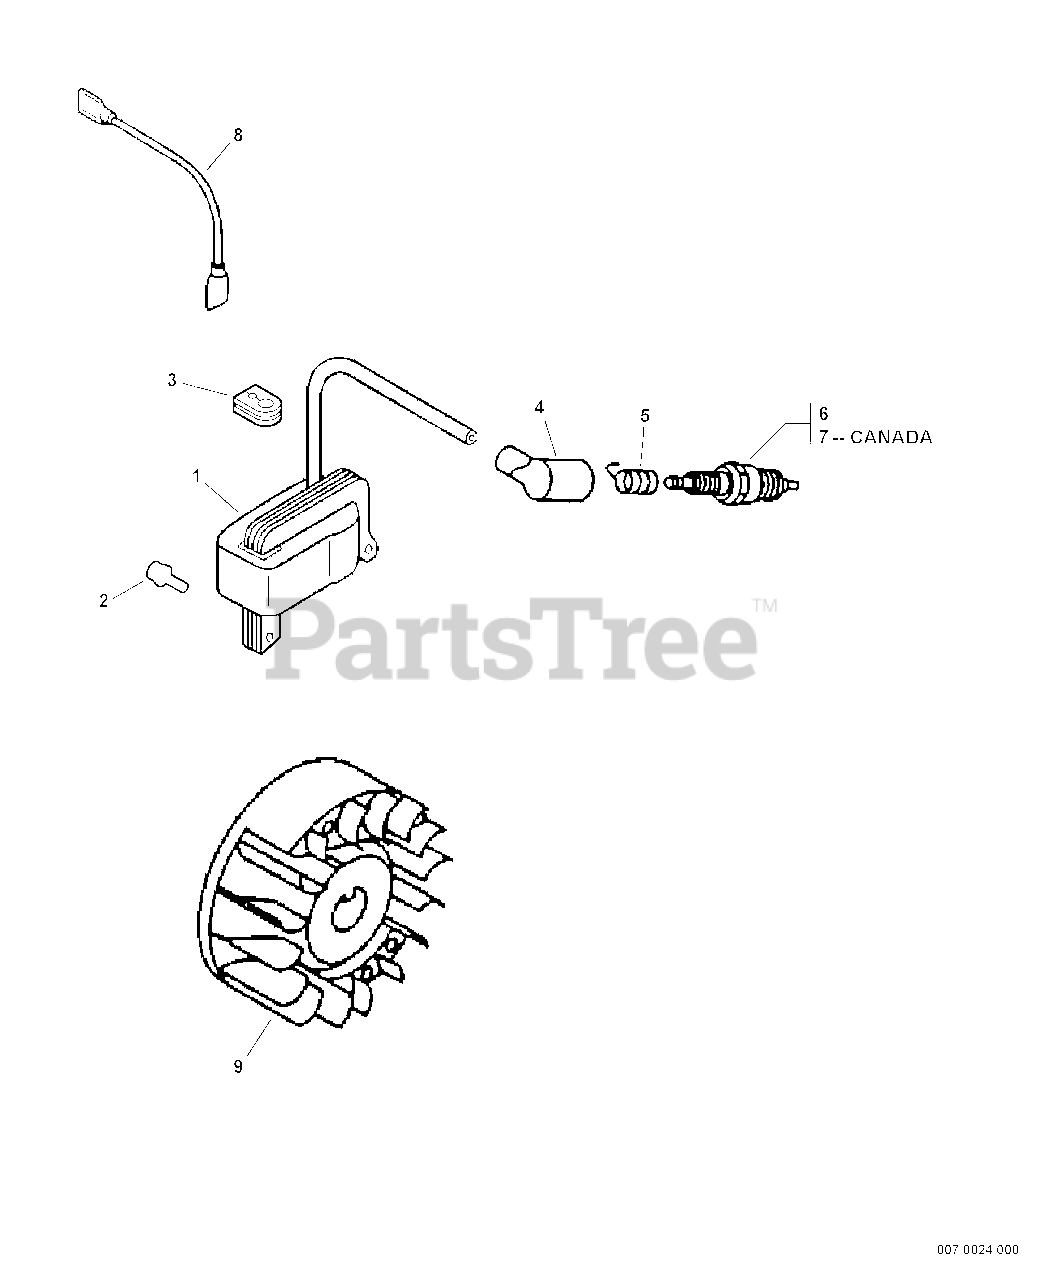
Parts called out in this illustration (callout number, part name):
1	COIL, IGNITION
2	BOLT 5×16
4	CAP, SPARK PLUG
5	TERMINAL, SPARK PLUG
6	SPARK PLUG - BPM8Y
7	SPARK PLUG - BPMR8Y
8	LEAD - IGNITION
9	FLYWHEEL
10	TUNE-UP KIT
11	TUNE-UP KIT
